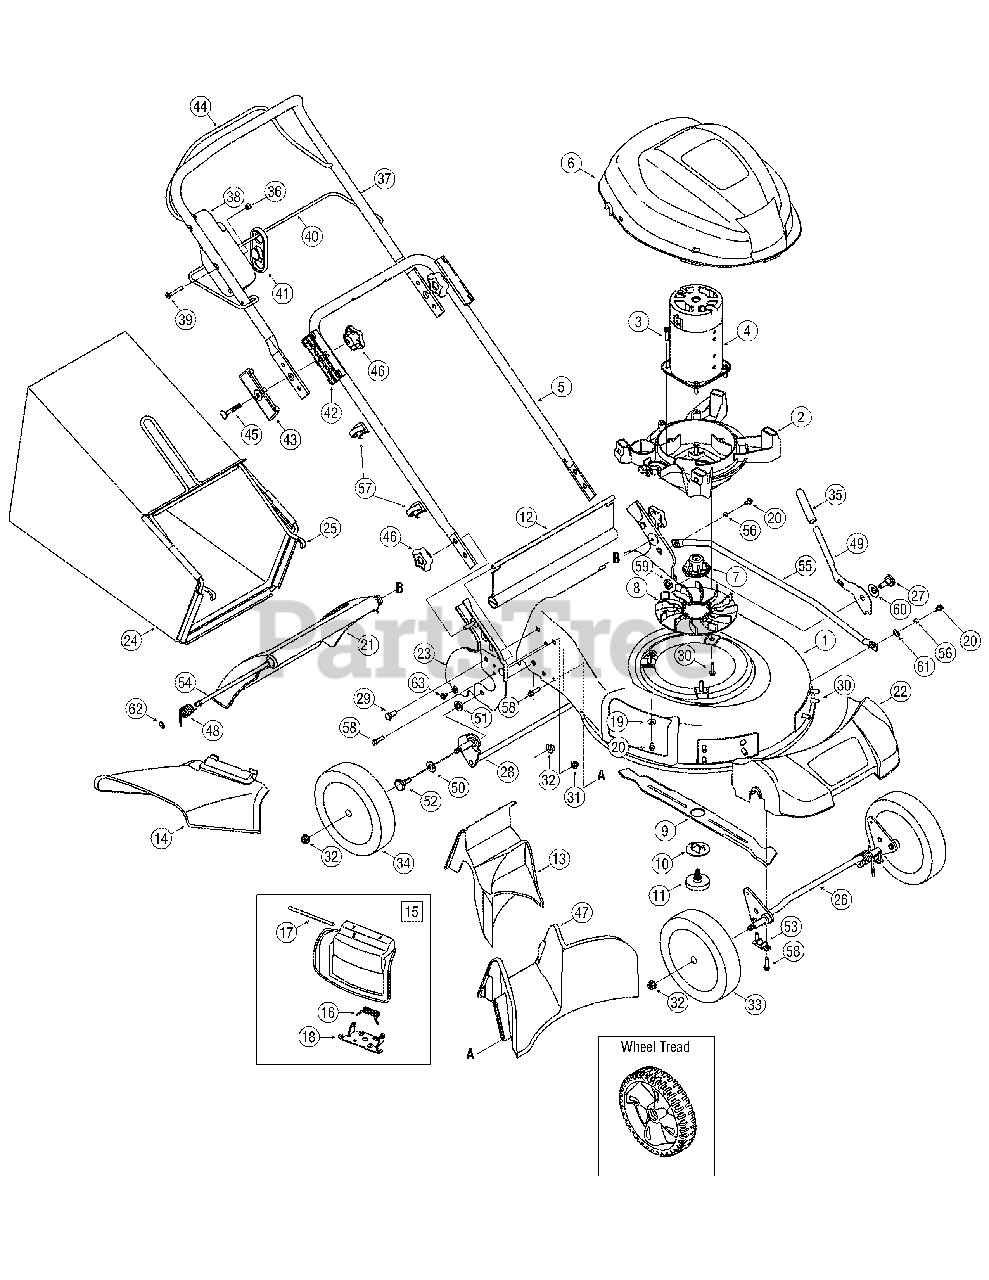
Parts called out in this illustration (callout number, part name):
2	Motor Bracket
3	Screw, 1/4-15 x .750
4	Electric Motor, 120V
6	Motor Shroud
7	Blade Hub
8	Electric Fan
9	Mulching Blade
10	Blade Locking Plate
11	Blade Bolt Assembly
12	Trail Shield
13	Rear Mulch Plug
14	Side Discharge Chute
15	Mulch Plug
16	Torsion Spring
17	Hinge Pin
18	Chute Deflector Adapter
19	Beleville Washer
21	Rear Door
22	Front Cover
24	Grass Bag
27	Screw, Shoulder, .50 x .66
29	Screw, 5/16-18 x .625
30	Screw, 5/16-14 x .750
31	Nut, Flange Lock, 5/16-18
32	Nut, Flange Lock, 3/8-16
33	Front Wheel
34	Rear Wheel
35	Foam Grip
36	Nut, Hex Lock, 1/4-20
37	Upper Handle
38	Motor/Blade Control
39	Screw, Flat, 1/4-20 x 1.75
40	Guide Rod
42	Lower Handle Insulator
43	Upper Handle Insulator
44	Motor/Blade Control Handle
45	Bolt Carriage, 5/16-18 x 2.0
46	Star Knob
47	Rear Baffle
48	Door Torsion Spring - RH
48	Door Torsion Spring - LH
49	Spring Lever
50	Washer, Flat, .510 x 1.00 x .060
51	Washer, Flat, .531 x .875 x .15
52	Screw, Shoulder, .500 Dia. X .434
53	Bushing, Lock, .505 Dia. X .62
54	Rear Door Pivot Rod
57	Cable Guide
58	Screw, 1/4-15 x 1.000
59	Spacer, .515 x 1.00 x .310 Lg.
60	Washer, Bell, .510 x 1.14 x .040
61	Washer, Wave, .390 x .825 x .016
62	Nut, Speed
63	Screw, #10-16 x .375
